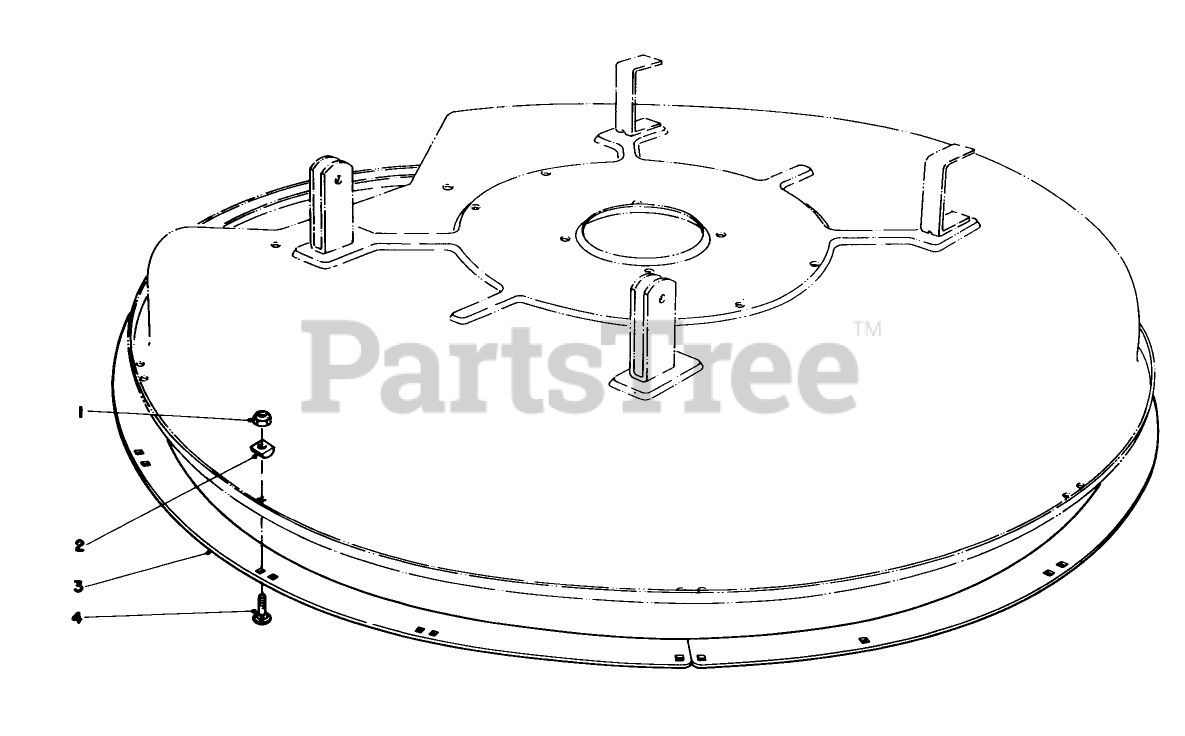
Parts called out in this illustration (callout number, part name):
1	NUT-LOCK, NI
2	Spacer-Deck Ring
3	DECK RING *B
4	BOLT-CARR
